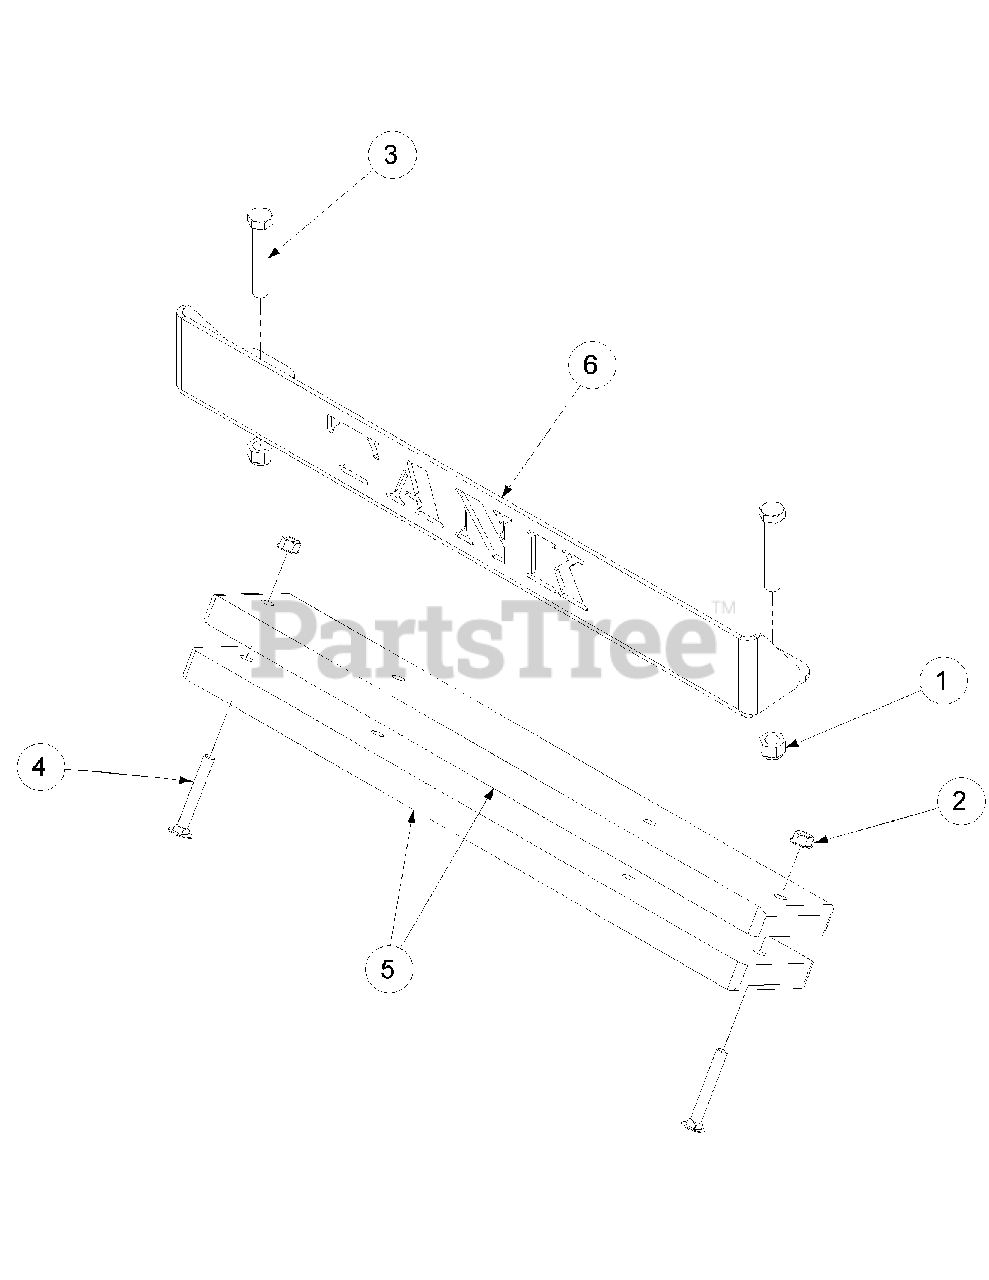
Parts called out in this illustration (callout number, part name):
1	Hex Nut, 1/2-13, Insert Lock
2	Nut, Hex 3/8-16 Flange Lock
3	HHCS, 1/2-13, 3.00
4	Carriage Bolt, 3/8-16 x 2.75
5	Bar, Weight
6	Rear Bumper Plate
